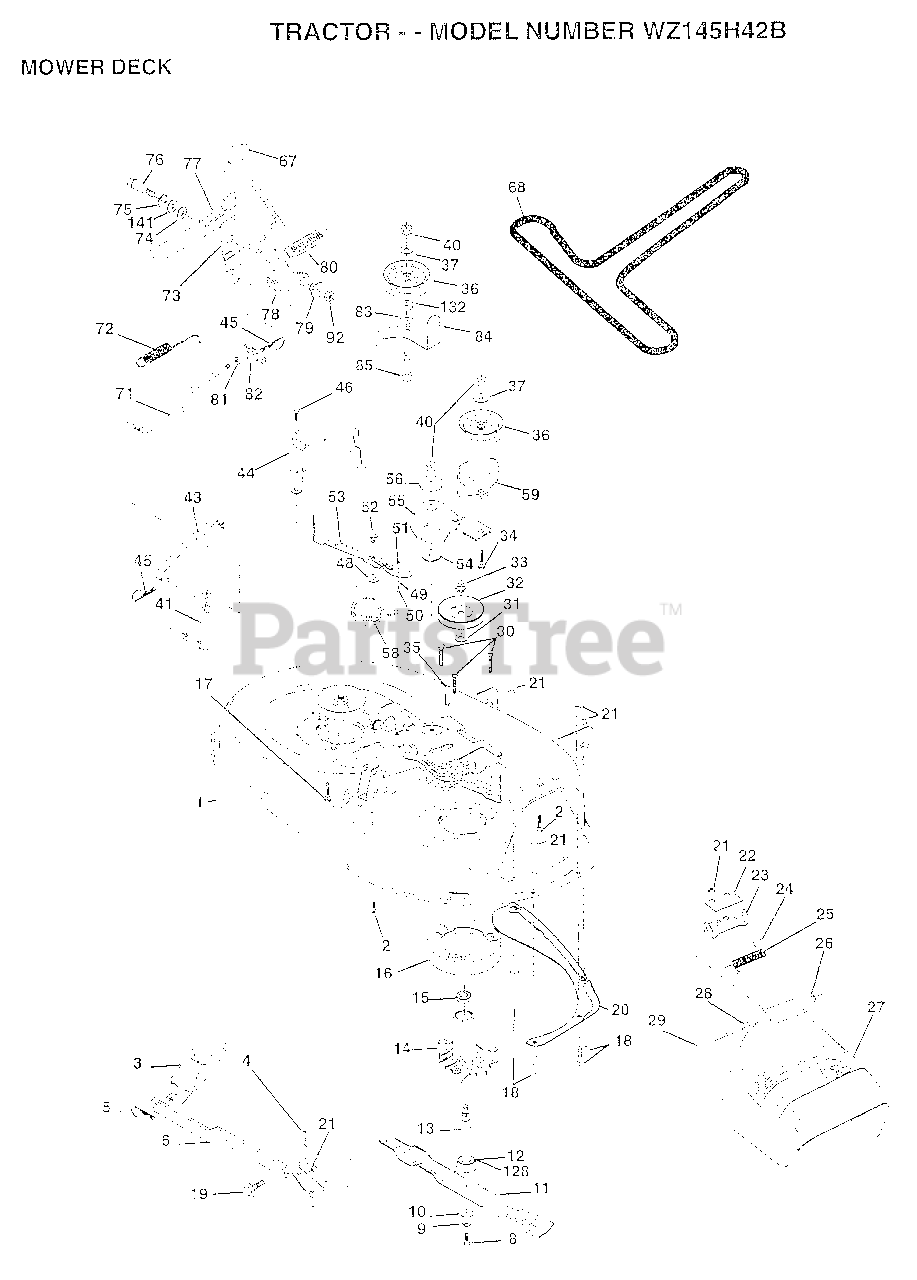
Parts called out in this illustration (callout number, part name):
1	"HOUSING ASSY.42"""
2	BOLT
3	BRKT ASM SWAY BAR
4	BRKT DECK SW BAR
8	BLADE BOLT
10	WASHER.HARD.BLADE
11	"BLADE.42"" HIPERF"
12	BEARING.BALL
14	HSG ASM MANDREL
15	BEARING
16	STRIPPER RND MWR
17	BOLT RDHD 3/8-16
18	BOLT
19	BOLT SHD 5/16-18
20	BAFFLE VORTEX 42
22	STIFFENER BRKT
23	DEFLECTOR BRKT
25	SPRING TORSION
27	DEFLECTOR.SHIELD
28	WASHER
29	HINGE ROD
30	"SCREW-THD ROLL,WA"
31	WASHER
32	PULLEY.MANDREL.42
34	BOLT
35	XMAS TREE FASTNER
36	FLAT IDLER PULLEY
37	WASHER
41	PIVOT ROD
43	ROD CLUTCH W/NIBS
44	GUARD MAND LH BLK
46	SCREW.1/4-20X5/8
48	HARD SMALL WASHER
49	ROLLER ASM-CAM
50	SHOULDER BOLT
51	LOCKNUT
52	BOLT.SHLD.5/16-18
53	BRAKE PAD ARM ASM
54	HARDENED WASHER
55	ARM-IDLER
56	SPACER RETAINER
58	SPRING TORSN BRAK
59	GUARD IDLER TUV
67	KNOB.RD.7/16-14
68	BELT.V.T-PATH
71	ROD CLUTCH 38/42
72	RETURN SPRING
73	CLUTCH ARM SECOND
74	WASHER
75	RING
76	SHOULDER BOLT
77	SPRING KEEPER
78	LEVER.ASM.CLUTCH
79	BUSHING
80	SPRING.CLUTCH.MWR
81	NUT
82	TRUNION ADJ
83	WASHER
84	"KEEPER-BELT,FIXED"
85	BOLT
92	NUT
128	WASHER.FELT.
132	WASHER GT
141	WASHER .T
